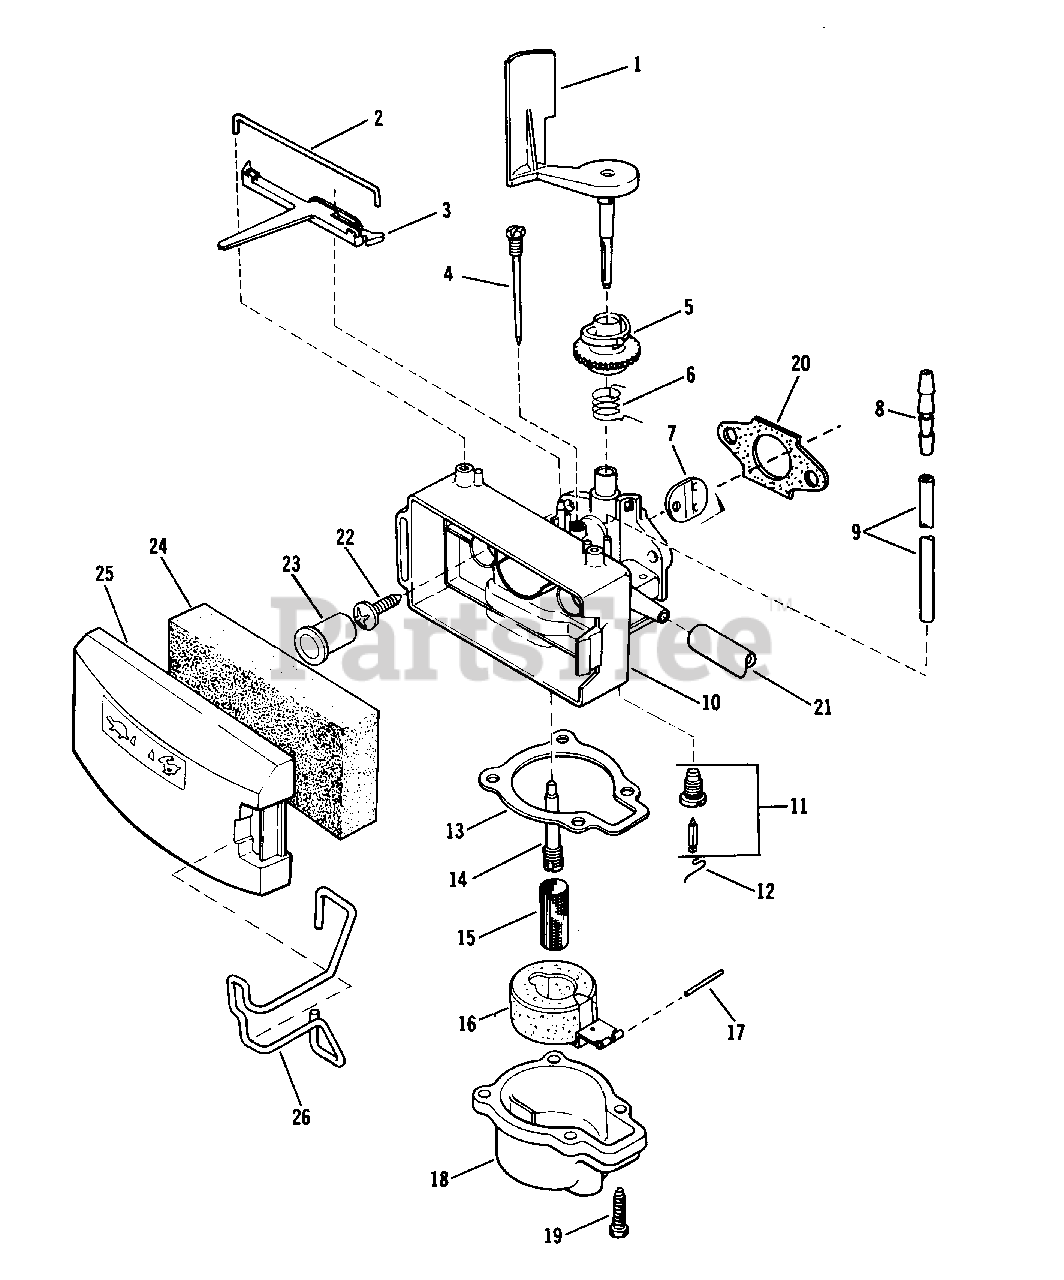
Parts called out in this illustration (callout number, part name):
1	Air Vane and Shaft
2	Retainer-Speed Control Lever
3	Speed Control Lever
4	Needle Adj. Ass'y.
5	Collar
6	Spring
7	Disc-Throttle
8	Connector-Reducer
9	Tube-Primer
10	Carburetor Body
11	Float Valve and Seat Ass'y.
12	.Clip
13	Gasket
14	Nozzle
15	Filter-Carburetor
16	Float and Arm Ass'y.
17	Pin-Float
18	Float Chamber
19	Screw-Float Chamber
20	Gasket-Carb. to Crankcase Cover
21	Fuel Line
22	Screw-Carb. Mounting
23	Plug
24	Element-Air Filter
25	Cover-Air Filter
26	Retainer-Filter Cover
